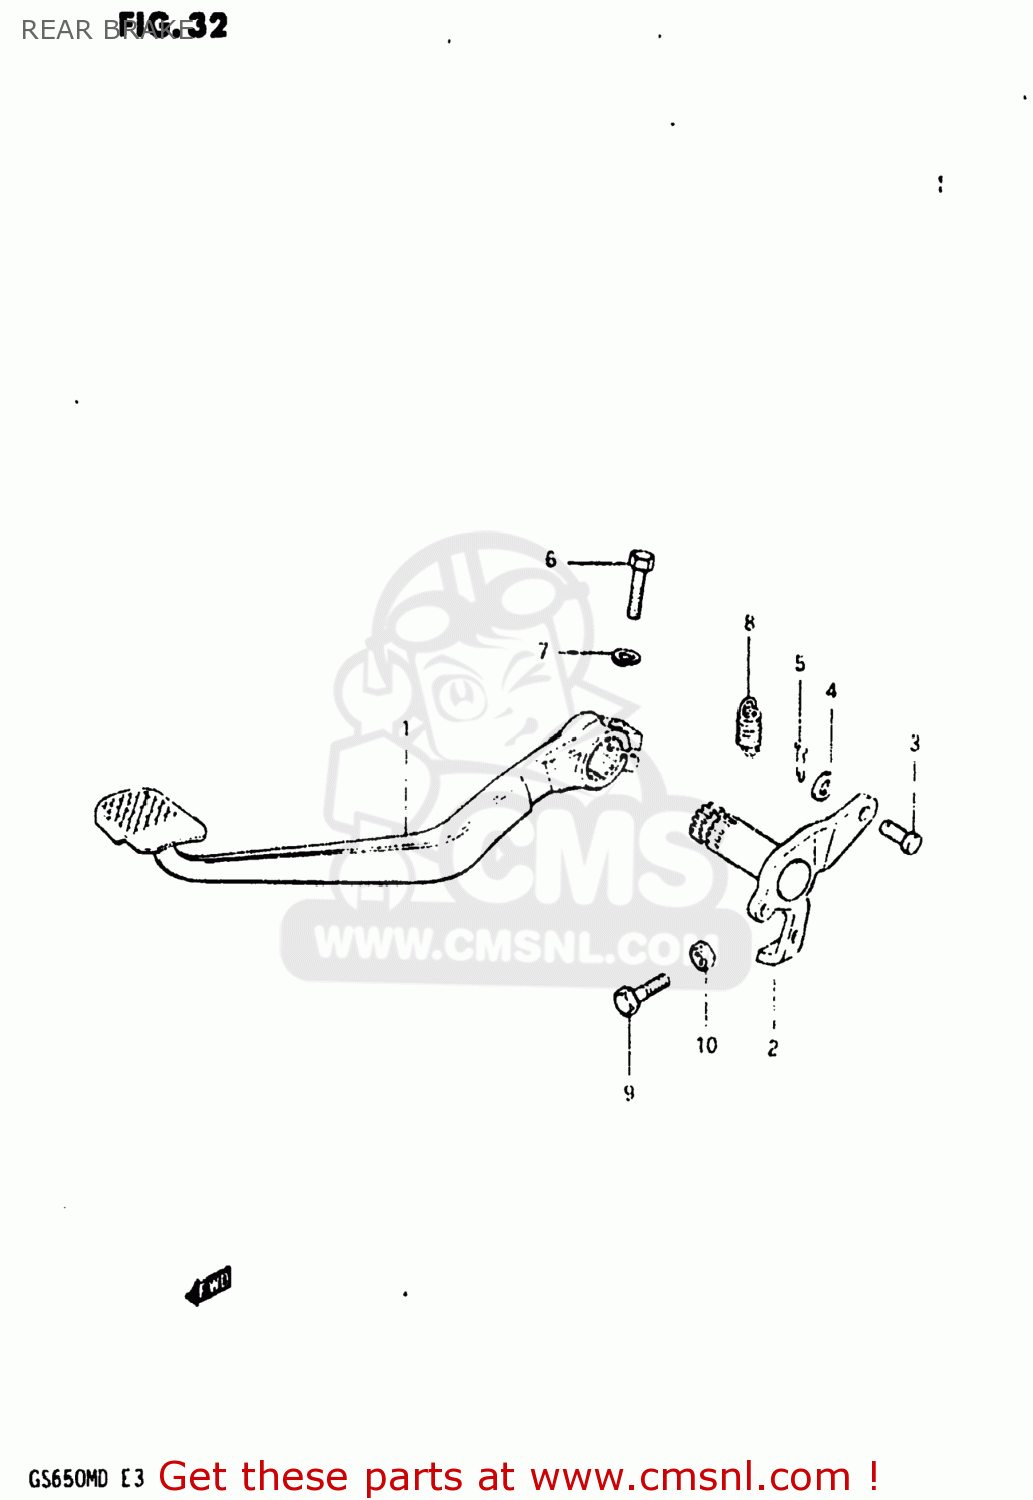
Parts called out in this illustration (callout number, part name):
1	PEDAL,BRAKE
2	ARM,BRAKE PEDAL ROD
3	PIN
4	WASHER
5	PIN
6	BOLT
7	LOCK WASHER
8	SPRING
9	BOLT
10	NUT
